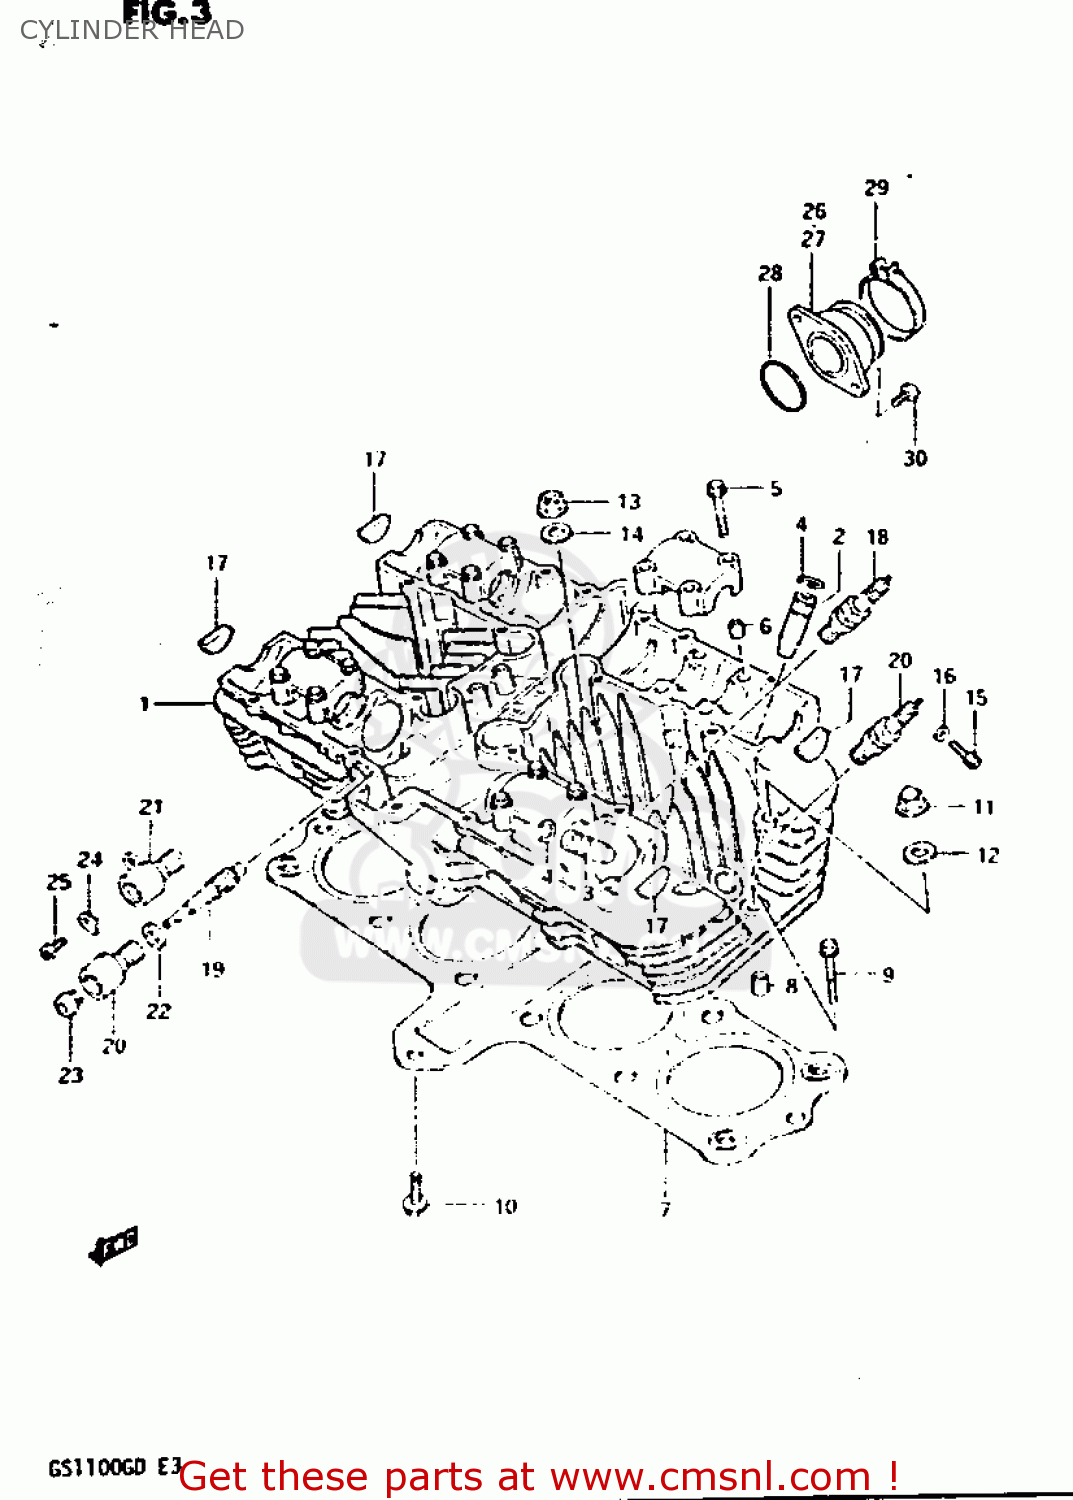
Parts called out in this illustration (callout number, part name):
1	HEAD ASSEMBLY,CYLINDER
2	GUIDE,INTAKE VALVE
3	GUIDE,EXHAUST VALVE
4	RING,SNAP
5	BOLT(6X39)
6	PIN(6.2X8X11)
7	GASKET,CYLINDER HEAD (NAS)
8	PIN
9	BOLT,UNDER
10	BOLT
11	NUT
12	GASKET(10.5X22X2) (NAS)
13	NUT
14	WASHER(10.5X22X2.3)
15	SCREW (5X10)
16	GASKET(5.3X9.3X1.2) (NAS)
17	PLUG
18	PLUG,SPARK
19	GEAR,TACHOMETER DRIVEN
20	SLEEVE,TACHOMETER DRIVE GEAR
21	SLEEVE,TACHOMETER DRIVE GEAR
22	SEAL,TACHOMETER DRIVEN
23	SEAL,OIL(5X12X8)
24	PLATE,TACH DRIVE GEAR SLEEVE
25	SCREW(5X12)
26	PIPE,INTAKE,R
27	PIPE,INTAKE,L
28	O-RING (D:2.4 ID:39.7)
29	CLAMP
30	SCREW
